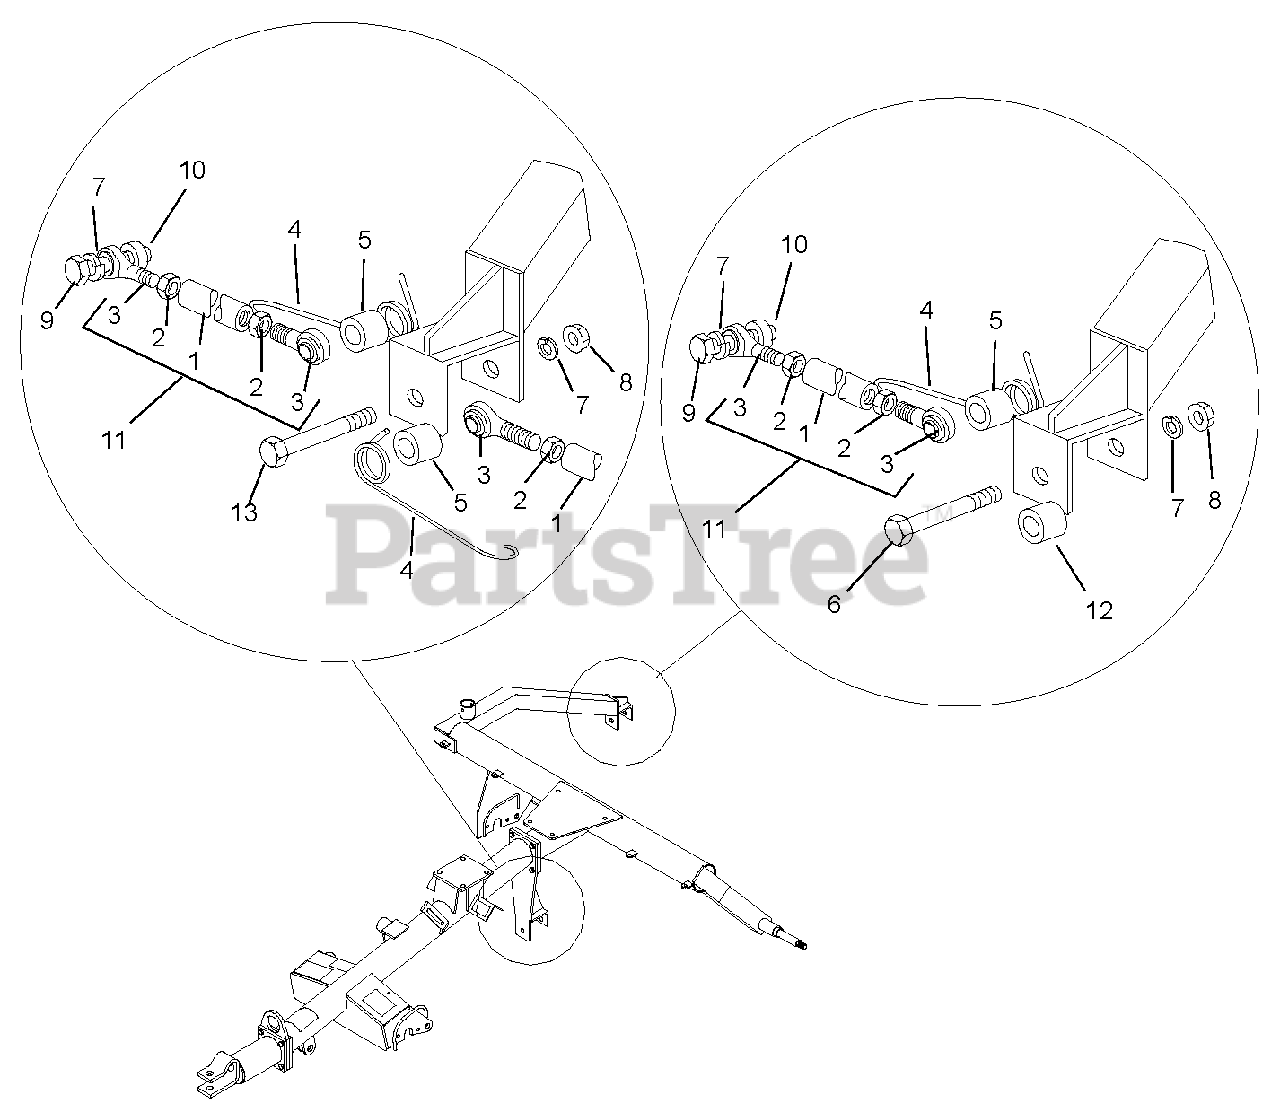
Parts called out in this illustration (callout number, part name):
1	Tie Rod, Rear
2	Nut, Hex .625-18 Right Hand Thread
3	Rod End, .625 Bore, Left Hand Thread
4	Spring, Compensator .25
5	Spacer, Compensator Long
6	Cap Screw, Hex Head .625-11 x 3.75
7	Washer, Lock .625
8	Nut, Hex .625-11
9	Cap Screw, Hex Head .625-11 x 2
11	Tie Rod Assembly, Short
12	Spacer, Compensator Short
13	Cap Screw, Hex Head .625-11 x 4.75
